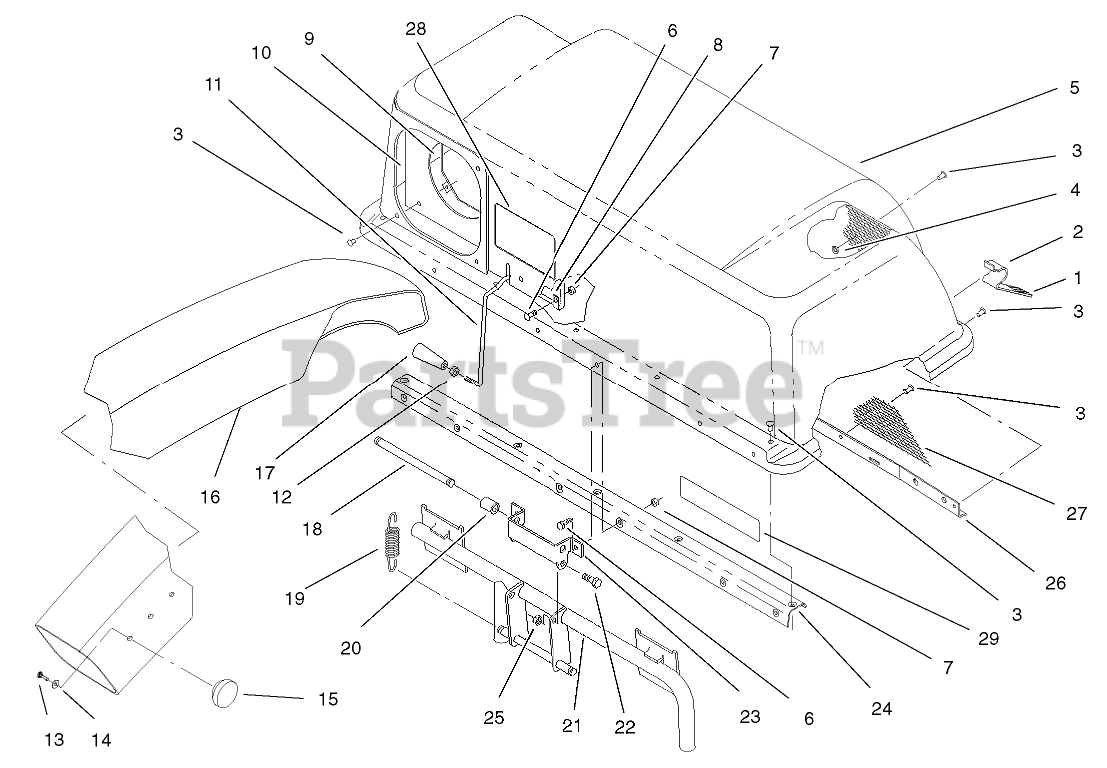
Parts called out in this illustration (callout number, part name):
2	LATCH-BAGGER, TOP
3	RIVET-BLIND
4	WASHER-FLAT
5	TOP-BAGGER
6	SCREW-HH
7	NUT-LOCK, NI
8	CLAMP
9	CLAMP-SEAL
10	SEAL-CHUTE
11	FEELER-FILL, BAG
12	NUT-JAM
13	SCREW-PPHTF
14	WASHER-PLAIN
16	CHUTE-DISCHARGE
17	HANDLE-TAPERED
18	PIN-SPRING
19	SPRING-EXTENSION
20	Spacer
21	FRAME ASM
22	SCREW-HH
23	Hinge-Bag, Top
24	STIFFENER ASM
25	NUT-LOCK, NI
26	SUPPORT-SCREEN
27	SCREEN-BAGGER
28	DECAL
29	DECAL-CAUTION
